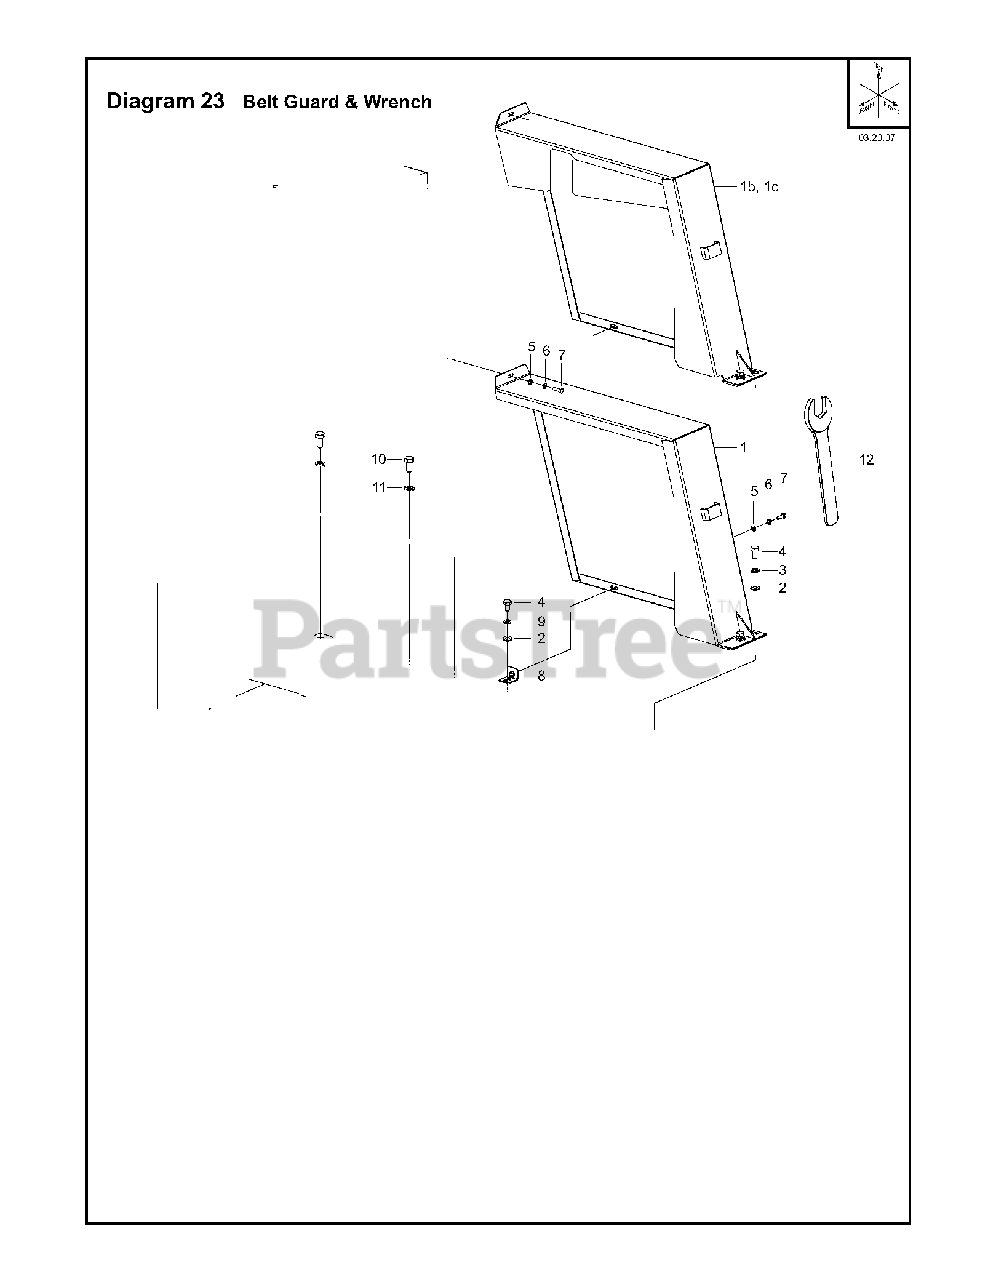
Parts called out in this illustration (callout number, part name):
3	LOCKWASHER. SPLIT M10
4	HHCS. M10 x 1.5 x 20 DIN933 ZP
5	WASHER
6	LOCKWASHER. SPLIT M6
7	GRIP HANDLE DLM
8	BELT GUARD MOUNT TAB. BLACK
9	LOCKWASHER. EXTERNAL STAR M10
10	HHCS. M12 x 1.75 x 25 DIN933ZP
11	LOCKWASHER. SPLIT .5 Z/P
12	WRENCH. OPEN END 1-1/2"
